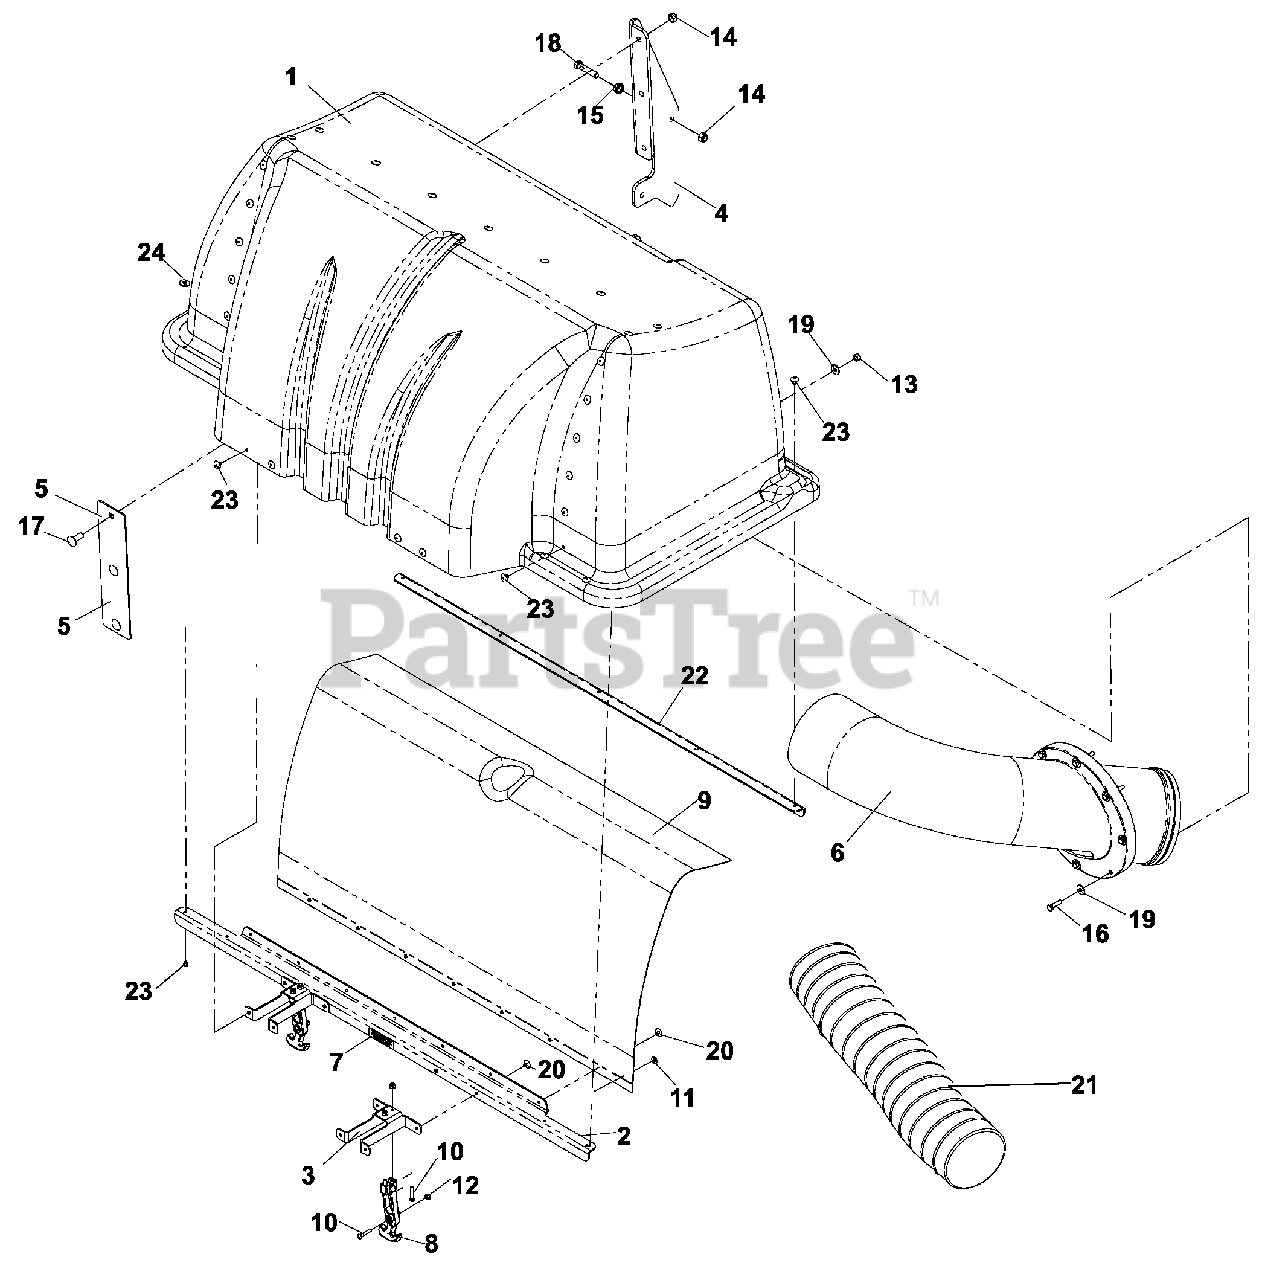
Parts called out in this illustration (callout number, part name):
2	HOOD SUPPORT
3	SUPPORT, DRAW LATCH
4	HOOD HINGE
5	MOUNT PLATE
6	INLET TUBE
7	DECAL, VENTILATION
8	DRAW LATCH, FLEXIBLE T-HANDLE
9	MESH, POLY DIAMOND
10	SCREW, #10-24 X 1 1/8, MACH.
11	WASHER, #10
12	NUT, #10-24, NYLOC
13	NUT, 1/4C, NYLOC
14	NUT, 3/8C, NYLOC
16	HCS, 1/4-20 X 1 3/4
17	RHSNB, 3/8-16 X 1
18	HCS, 3/8-16 X 1 3/4
19	WASHER, 1/4
20	RIVET, 3/16 X 1/4
21	HOSE, 58", MODEL HCS13
22	HOOD SUPPORT, REAR
23	RIVET, 1/4 STAVEX
24	WASHER, #10
